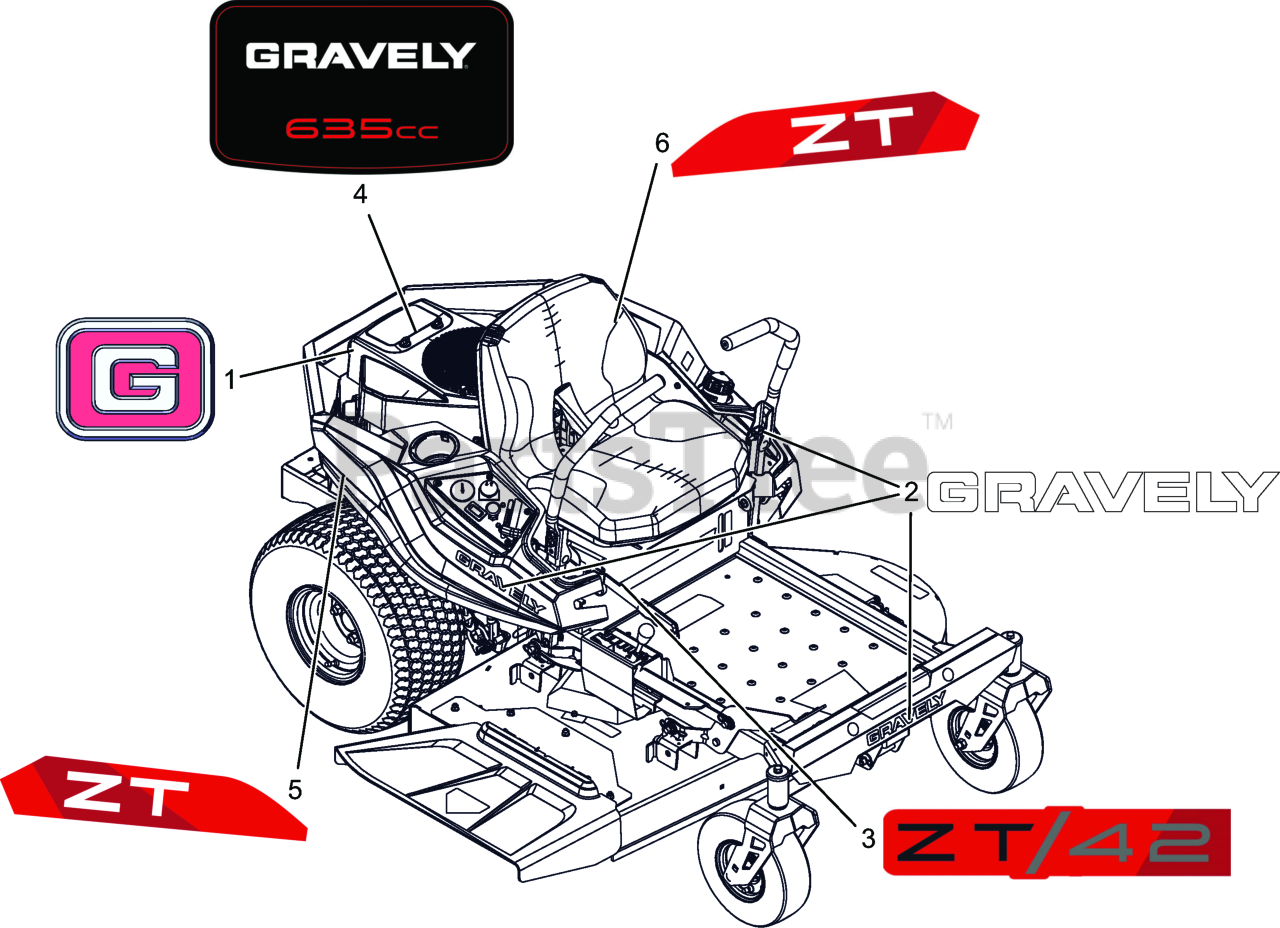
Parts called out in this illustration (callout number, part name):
1	DECAL, GRAVELY BRAND
2	DECAL, 9.5" GRAVELY LOGO
3	DECAL, GRAVELY ZT / 42
4	DECAL, ENGINE 635CC
5	DECAL, ZT RH FENDER
6	DECAL, ZT LH FENDER
